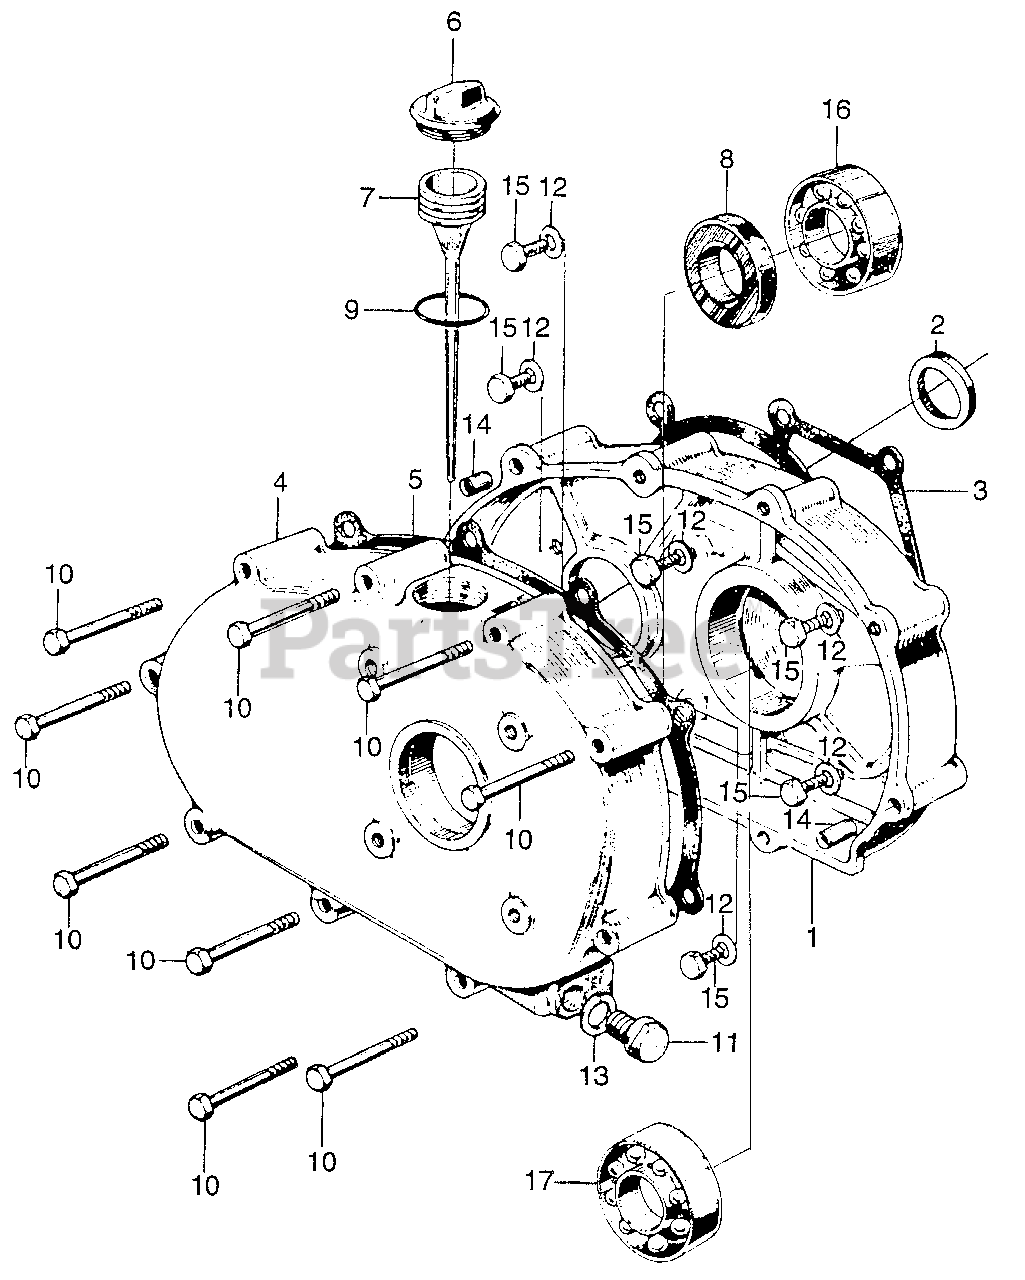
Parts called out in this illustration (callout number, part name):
1	CASE, REDUCTION
2	ADAPTER, RING
3	GASKET, REDUCTION CASE (NOT AVAILABLE)
4	COVER, REDUCTION
5	GASKET, REDUCTION
6	CAP, REDUCTION OIL
6	CAP, REDUCTION OIL (GRAY)
7	DIPSTICK, OIL (NOT AVAILABLE)
8	OIL SEAL (PJ30507)
9	O-RING (26X2.7)
10	BOLT, HEX. (6X56)
10	BOLT, HEX. (6X56) (NOT AVAILABLE)
11	BOLT, DRAIN PLUG (12MM)
12	WASHER, PLAIN (8MM)
13	WASHER, DRAIN PLUG (12MM)
14	PIN, DOWEL (8X10)
15	BOLT, HEX. (8X25) (NOT AVAILABLE)
16	BEARING, RADIAL BALL (6205)
17	BEARING, RADIAL BALL (6206)
